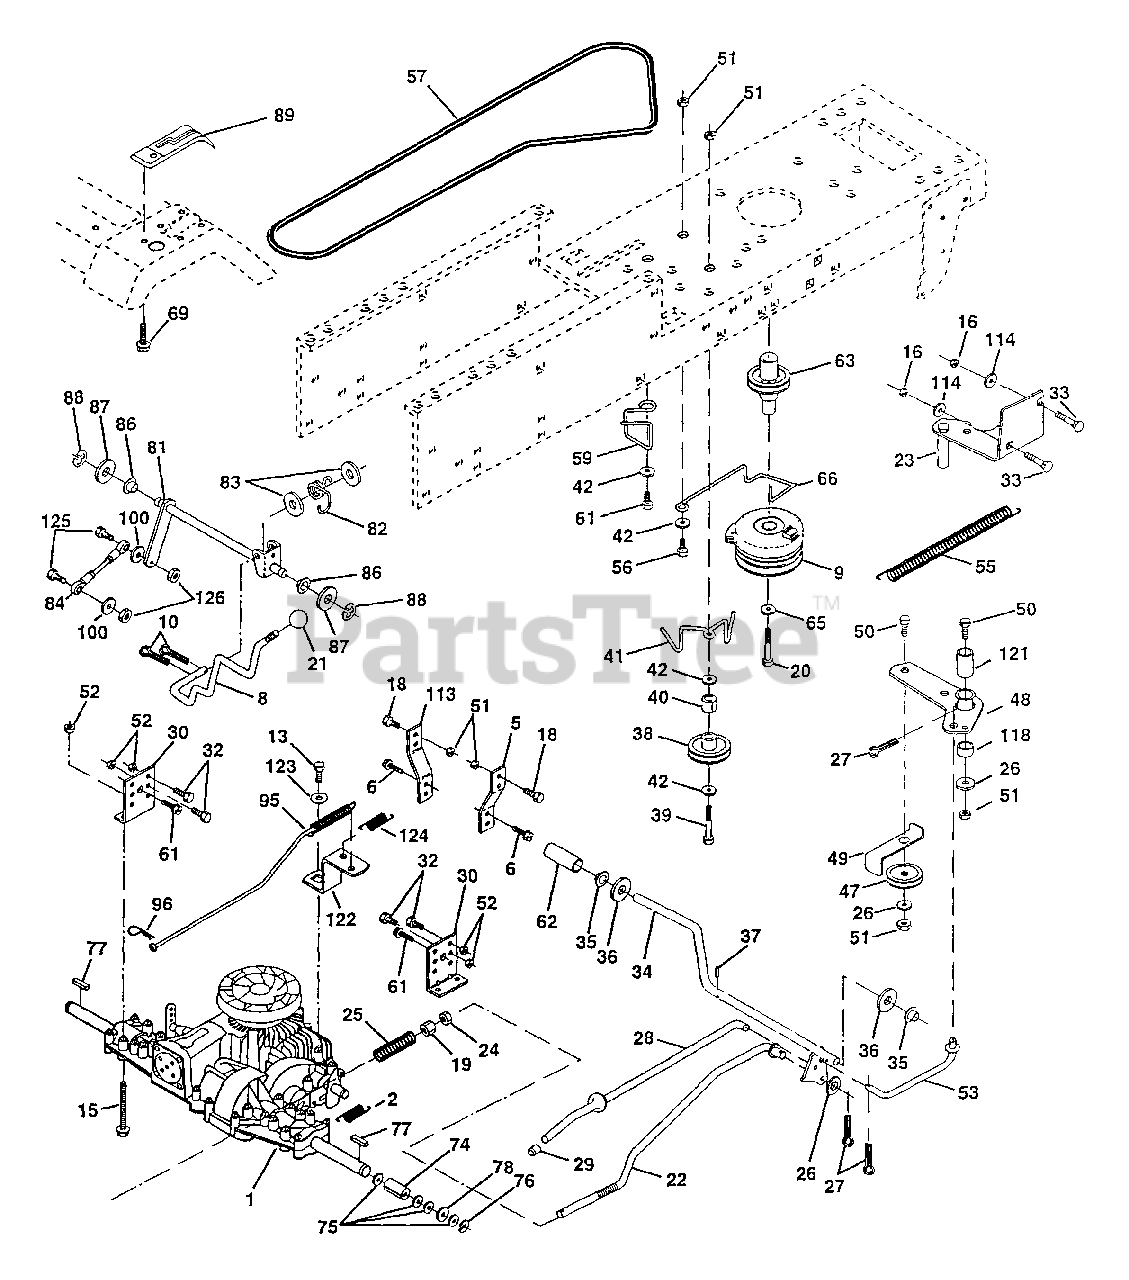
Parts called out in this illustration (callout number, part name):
1	Transaxle
2	Spring, Return, Brake
3	Pulley, Transaxle Hydro 750 LT
5	Strap Torque R
6	Screw Thdrol 5/16-18 x 3/4
8	Rod Shift Fender STLT
9	Clutch Electric
10	Pin Cotter 1/8 x 1 CAD
13	Bolt 1/4-28 Unf Gr. 8 w/Patch
15	Bolt Hex 5/16-18 Unc Flghd
16	Nut Lock Hex W/Ins. 5/1 6-18 Unc P
18	Bolt Fin Hex 3/8-16 Unc x 1 Gr.5
19	Nut Lock Hex W/Ins 3/8-16 Unc
20	Bolt, Hex 7/16-20 x 4-1/4 Ga. 5
21	Knob, Duckhead 1/2-13 Unc Blk
22	Rod, Brake
23	Bracket Asm Mtg CL
24	Nut Hex Jam 3/8-16 UNC
25	Spring, Brake Rod
26	Washer (AYP part number)
27	Pin Cotter 1/8 x 3/4 CAD.
28	Rod, Parking Brake
29	Cap,Parking Brake
30	Bracket, Transaxle
32	Bolt Hex Hd 5/16-18 Unc x 3/4
33	Bolt Carriage 5/16-18 UNC x 3/4
34	Shaft, Foot Pedal
35	Bearing, Nylon
36	Washer
37	Pin, Roll (AYP part number)
38	Pulley, Idler, Flat
39	Bolt
40	Spacer Split
41	Keeper, Belt Idler
42	Washer 13/32 x 13/16 x 12 Ga
47	Pulley, Idler, V-Groove Plastic (AYP part number)
48	Bellcrank Assembly
49	Retainer, Belt Style Spring
50	Bolt (AYP part number)
51	Nut
52	Nut Crown Lock 5/16-18
53	Link, Clutch
55	Spring, Return, Clutch
56	Bolt, Fin Hex 3/8-16 UNC x 1 1/4
57	V-Belt, Ground Drive
59	Keeper, Center Span (AYP part number)
61	Screw Thdrol. 3/8-16 x 3/4 Ty. TT
62	Cover, Pedal
63	Pulley Clutch Electric EVX
65	Washer Lock Hvy HLCL Spr 7/16
66	Keeper Belt Engine
74	Spacer, Axle
75	Washer 25/32 x 1-1/4 x 16 Ga.
76	E-Ring
77	Key, Square
78	Washer 25/32 x 1-5/8 x 16 Ga
81	Shaft Asm. Cross
82	Spring Torsion T/A
83	Washer 17/32 x 3/4 x 16 Ga.
84	Rod, Tie PVST 20"
86	Bushing Rod Strig. 629/632 ID
87	Washer 21/32 x 1-1/4 x 16 Ga.
88	Ring Klip #5304-62
89	Console, Hydro Shift STLT
90	Nut Self Thd Wsh-hd 1/4 zinc
95	Rod Asm. Bypass Hydro
96	Retainer Spring 1" Zinc/Cad
100	Washer 11/32 x 3/4 x 16 Ga.
113	Strap Torque Lh
114	Washer 11/32 x 3/4 x 14 Ga.
118	Spacer Bellcrank
121	Nyliner Clutching STL
122	Plate Bypass PVST
123	Washer 9/32 x 5/8 x 16 Ga.
125	Bolt Fin Hex 5/16-18 Unc x 1.00
126	Nut Lock 5/16-18 Nc Thd (AYP part number)
